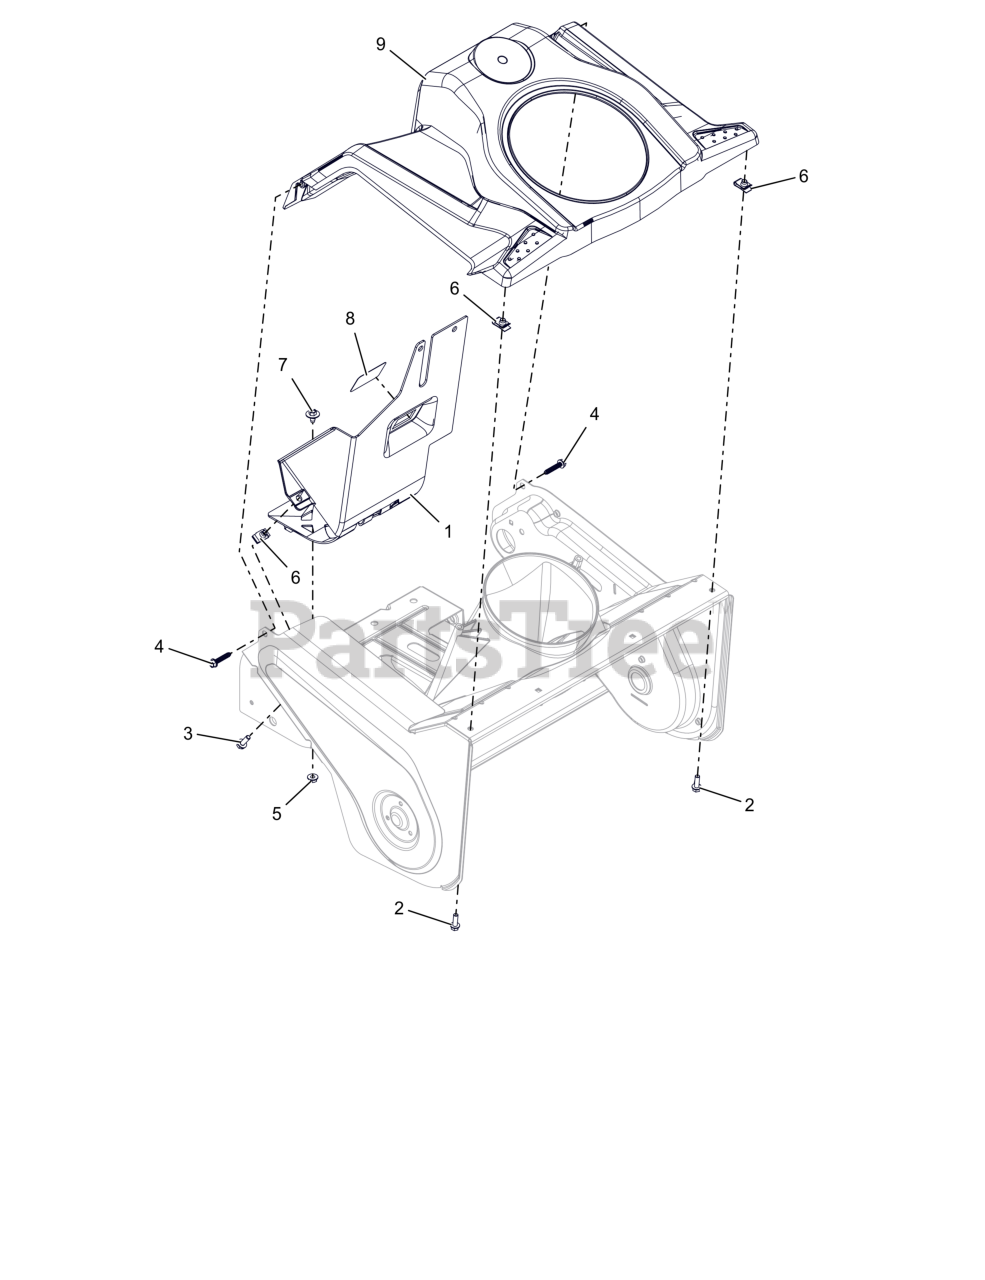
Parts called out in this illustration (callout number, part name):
1	COVER, BACK
2	BLT, HWH .25-20X.75 G5 ZCC
3	BLT,HEX-FLG .25-20X.75 G5 ZCC
4	SCR,PLASTITE .25-10X1.25 ZCC
5	NUT-LK-TOP-FLG .250-20 GF ZCC
6	NUT-RTNR .25-20X.56
7	SCR, TAP .25-20X.50 LG HWH ZCC
8	DECAL, REAR COVER
9	COVER, HOUSING - W/DECAL
